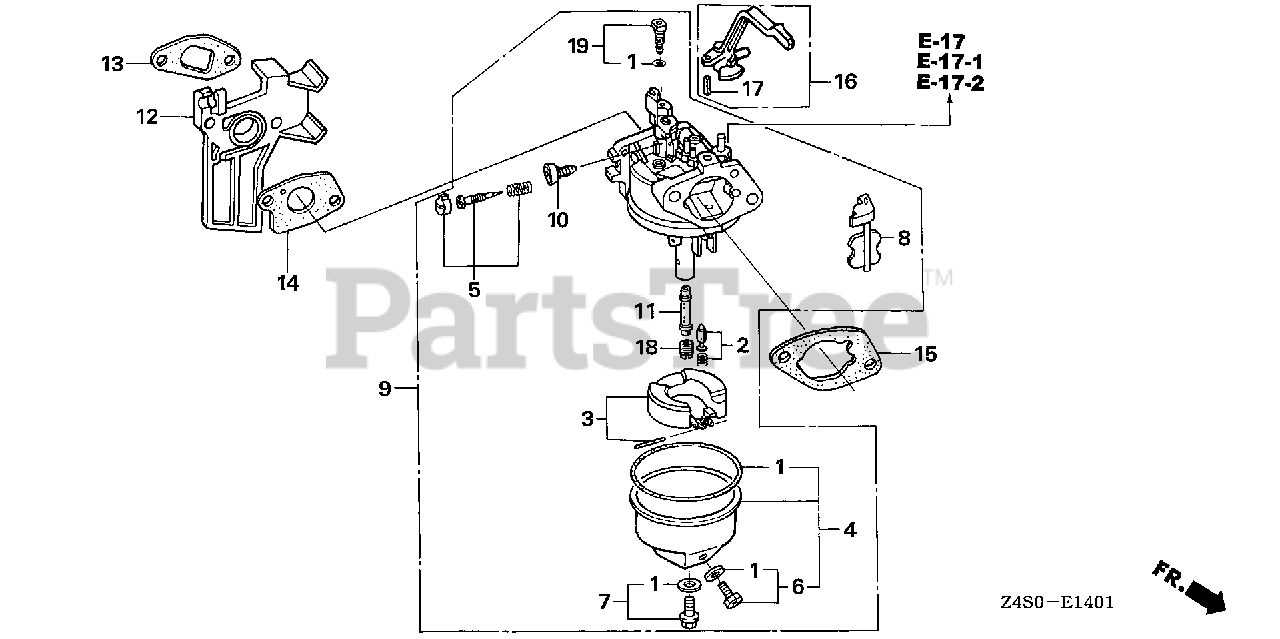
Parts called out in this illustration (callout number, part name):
1	GASKET SET
2	VALVE SET, FLOAT (SEAT NOT INCLUDED)
4	CHAMBER SET, FLOAT
5	SCREW SET, PILOT
6	SCREW SET, DRAIN
7	SCREW SET
9	CARBURETOR ASSY. (BE74A C)
9	CARBURETOR ASSY. (BE74N A)
10	SCREW, THROTTLE STOP
11	NOZZLE, MAIN
12	INSULATOR, CARBURETOR
13	GASKET, INSULATOR
14	GASKET, CARBURETOR
15	GASKET, AIR CLEANER
16	LEVER, CHOKE
17	PIN, SPRING (2X12)
18	JET, MAIN (#72)
18	JET, MAIN (#75)
18	JET, MAIN (#78)
19	JET SET, PILOT (#40)
